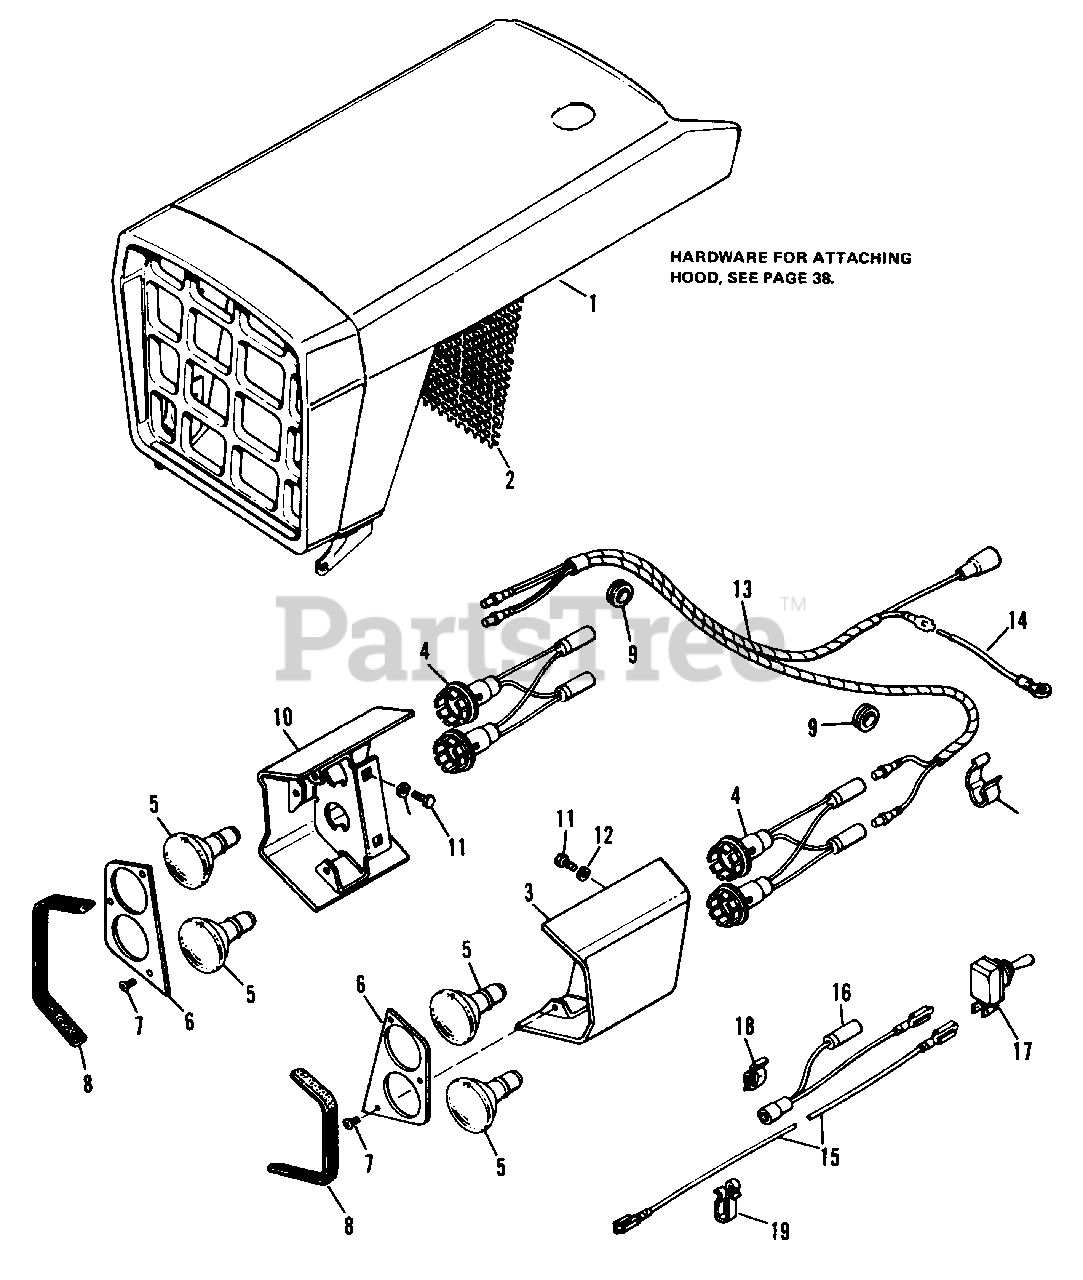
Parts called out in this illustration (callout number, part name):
1	HOOD & GRILLE ASSY
2	SCREEN, Grille
3	SHROUD & PLATE ASSY, L.H.
4	LAMP SOCKET & WIRE ASSY
5	HEAD LIGHT
6	PLATE, Front
7	SCREW, Thd. Forming, No. 12-24 x 1/2
10	SHROUD & PLATE ASSY, R.H.
11	CAPSCREW, Hex, 1/4-20 x 3/4
12	LOCKWASHER, 1/4
13	HARNESS ASSY
14	WIRE, Headlight to Ground
15	WIRE ASSY, Light
16	WIRE ASSY
17	SWITCH, Toggle
18	CABLE, Clip, Tinnerman
19	CABLE, Clip, Tinnerman
